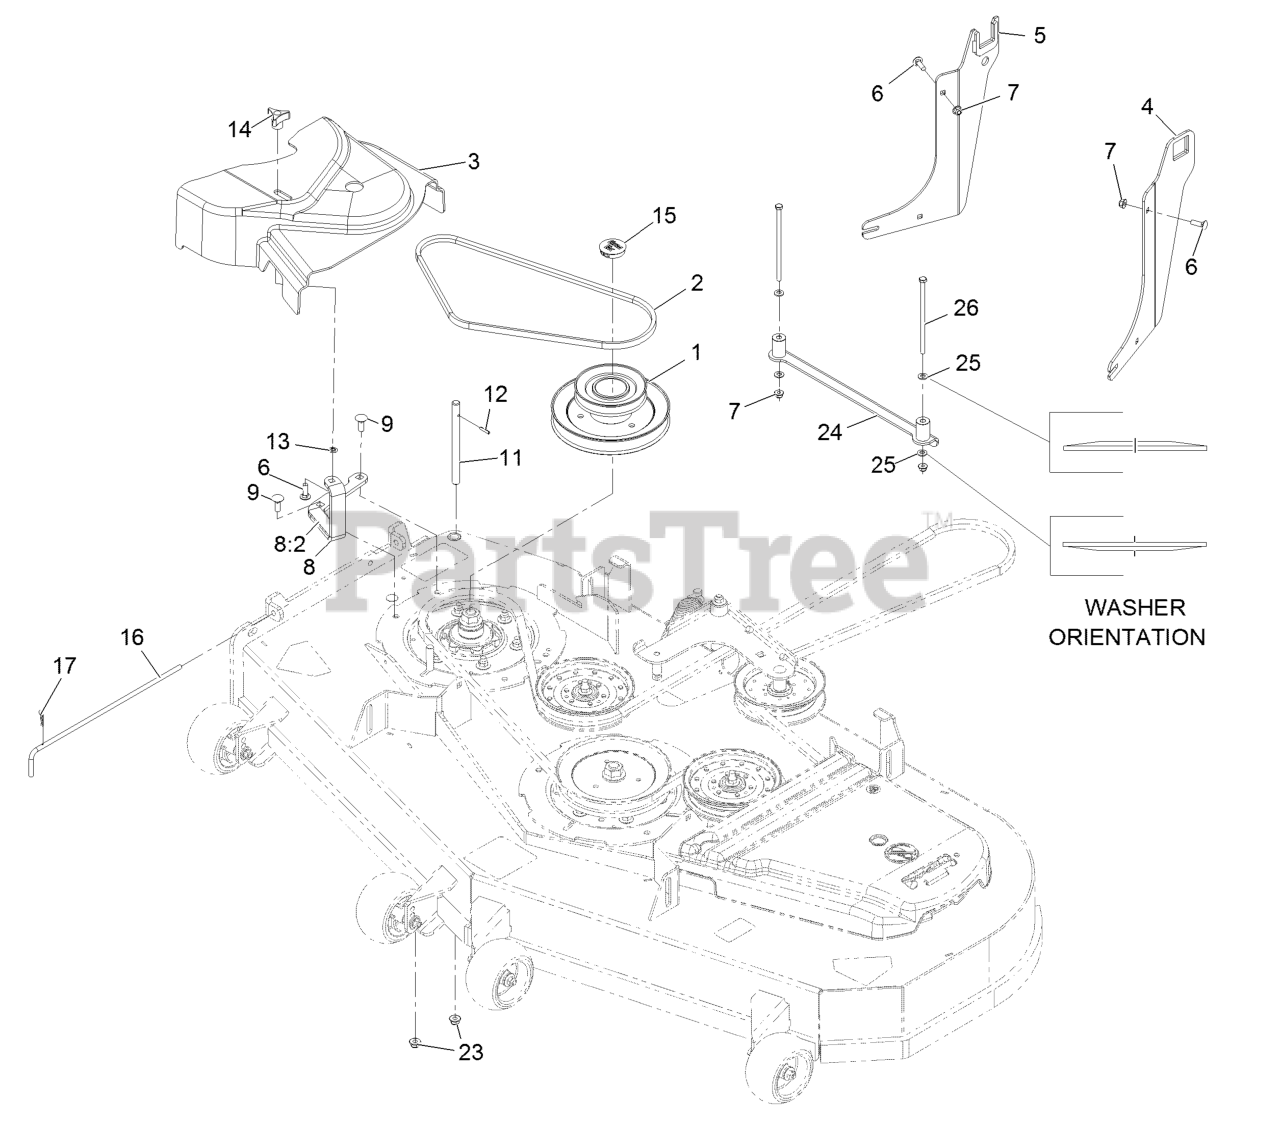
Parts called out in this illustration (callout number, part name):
1	JACKSHAFT,UV DRIVE 604 SPLINED
2	BELT,A 42.32
3	COVER-BELT UVE 60
4	BRACKET ASM, LH
5	BRACKET ASM, RH
6	BOLT-CARR
7	NUT-HF, NI
8	ASM-CVR BRKT W/DECAL
8:2	DECAL-COVER, MISSING
9	BOLT-CARR
11	SHAFT-CATCHER, GRASS
12	PIN-ROLL
13	RING-RETAINING, BOLT
14	KNOB-3 PRONG
15	PLUG, BLACK NYLON 1.75
16	PIN,CHUTE PIVOT
17	PIN-COTTER
23	Nut-Nyloc 3/8-16 Flg
24	ASM-HYDRO GUSSET
25	WASHER-SPRING
26	SCREW HH
